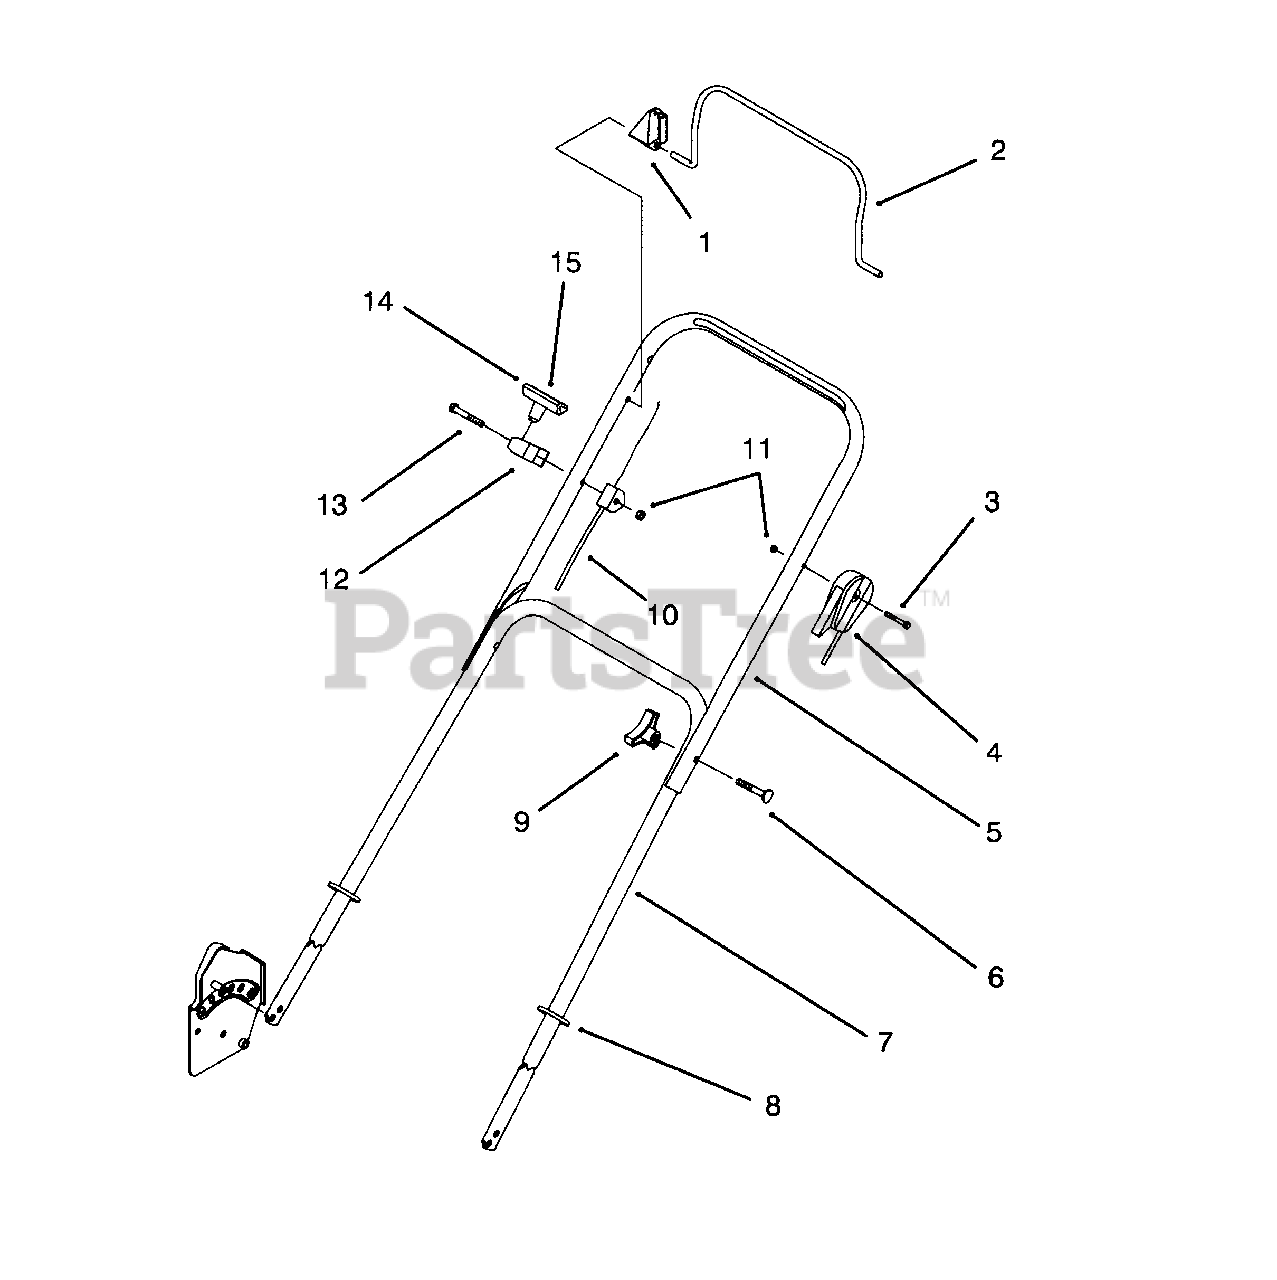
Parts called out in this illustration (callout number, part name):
1	Stop-Pivot
2	Bail-Flywheel Brake
3	Screw-Hex Hd. Cap
4	Cable-Throttle
5	Handle-Upper
6	Screw-Handle
7	Handle-Lower
8	Tie-Cable
9	Knob
10	Cable-Flywheel Brake
11	Nut-Lock
12	Guide-Rope
13	Screw-Hex Hd Cap
14	Handle-Starter
15	Clip-Rope Insert
